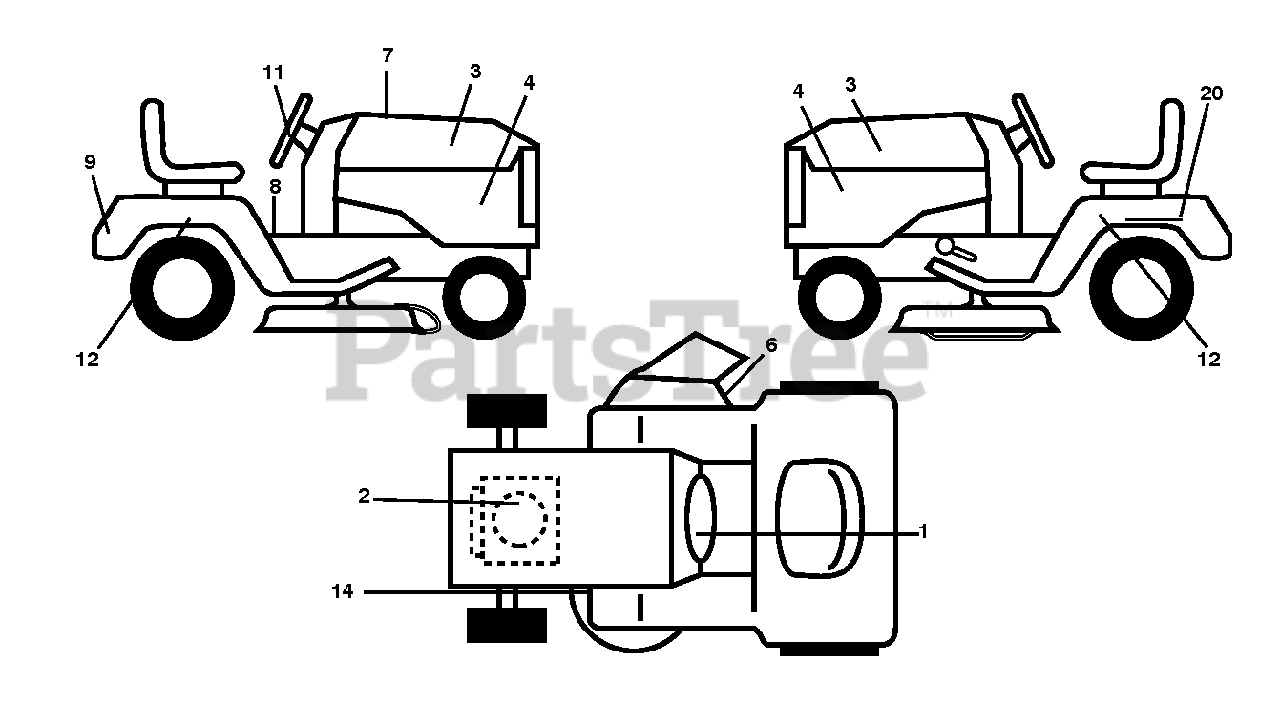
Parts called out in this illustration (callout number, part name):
1	DECAL, WARNING SPARK ARRESTOR
2	DECAL.ENG.BS.175INTK.
4	DECAL.SDPNL.RH/LHPAIR.175A46.P
6	DECAL.MOWER.WARN.KEEP.HAND.AWY
8	DECAL.FENDER.WARNING.ENGLISH
9	DECAL.REAR.FNDR.LOGO.POULAN.PR
11	DECAL.STEER.WHEEL.POULAN.PRO
14	DECAL.V-BELT.SCH.42/46"MEC/ELE
20	DECAL BTRY SYMBOLS
